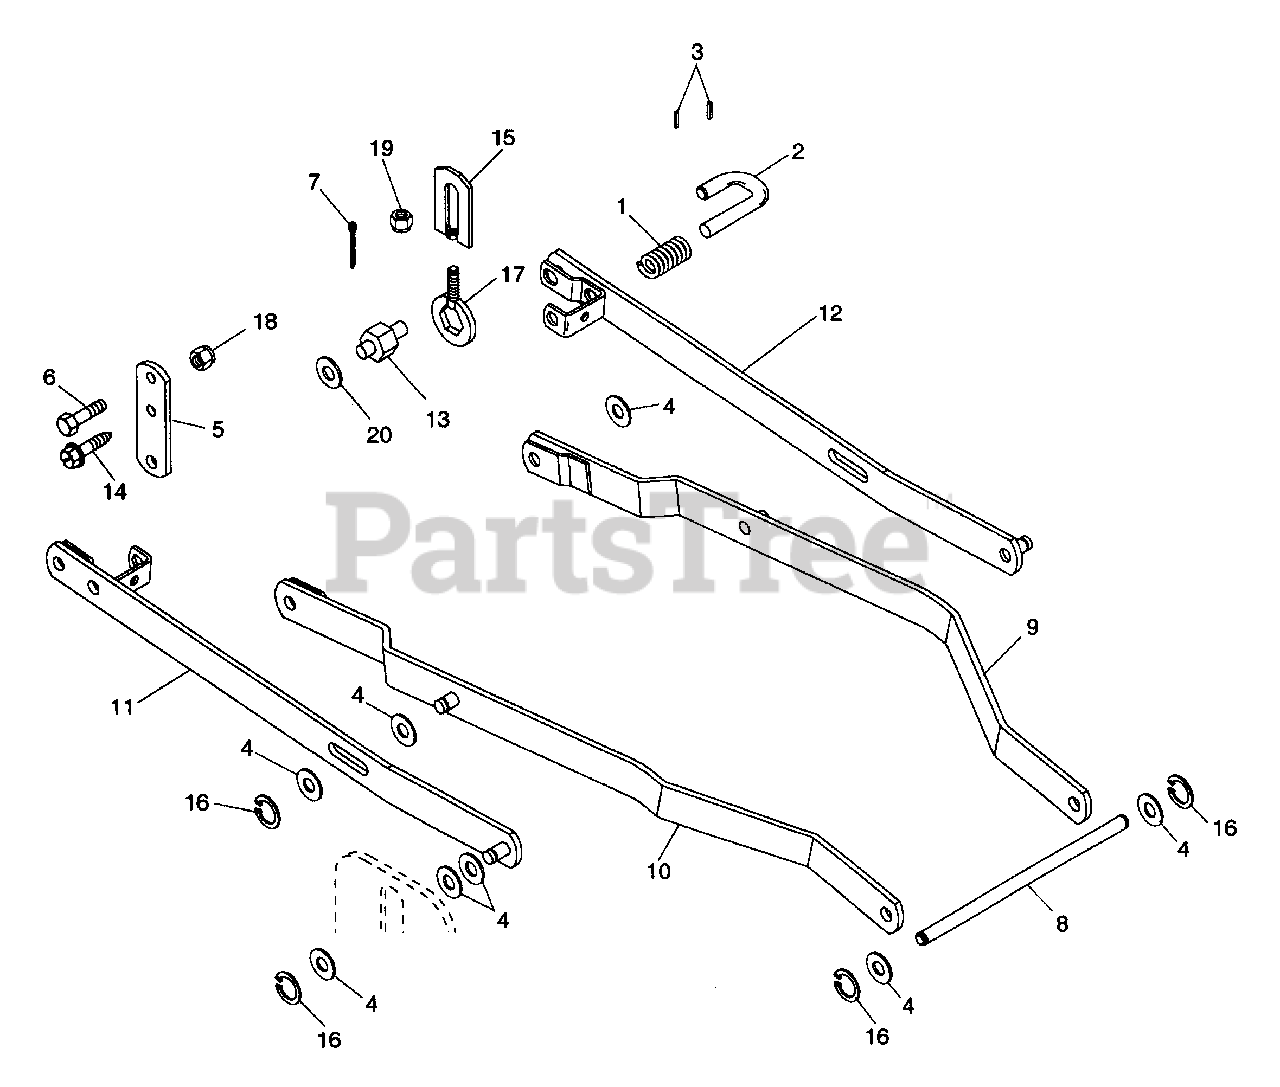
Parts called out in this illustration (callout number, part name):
1	SPRG, COMP .058X.65X2.13 WLD15
2	LATCH PIN
3	PIN-ROLL .125X.75
4	WSHR-FL-STL .531X1.062X.095 PL
5	HANGER BRACKET
6	BLT-HEX .38-16X.75 PL GR5
7	PIN-COTR .12X1.0 PL
8	PIN
9	LH LIFT ARM
10	RH LIFT ARM
11	REAR HANGER RH
12	REAR HANGER LH
13	HANGER PIVOT
14	SCR-TAP .375-16X1.0 HWH PL TR
15	LINK, ADJUSTMENT
16	RG-RTNG-EXT .500X.035
17	HEX HANGER
18	NUT-LK TOP .375-16 GR C YWZC
19	NUT-JAM .375-16 PL
20	WSHR-FL-STL .531X1.250X.100 PL
